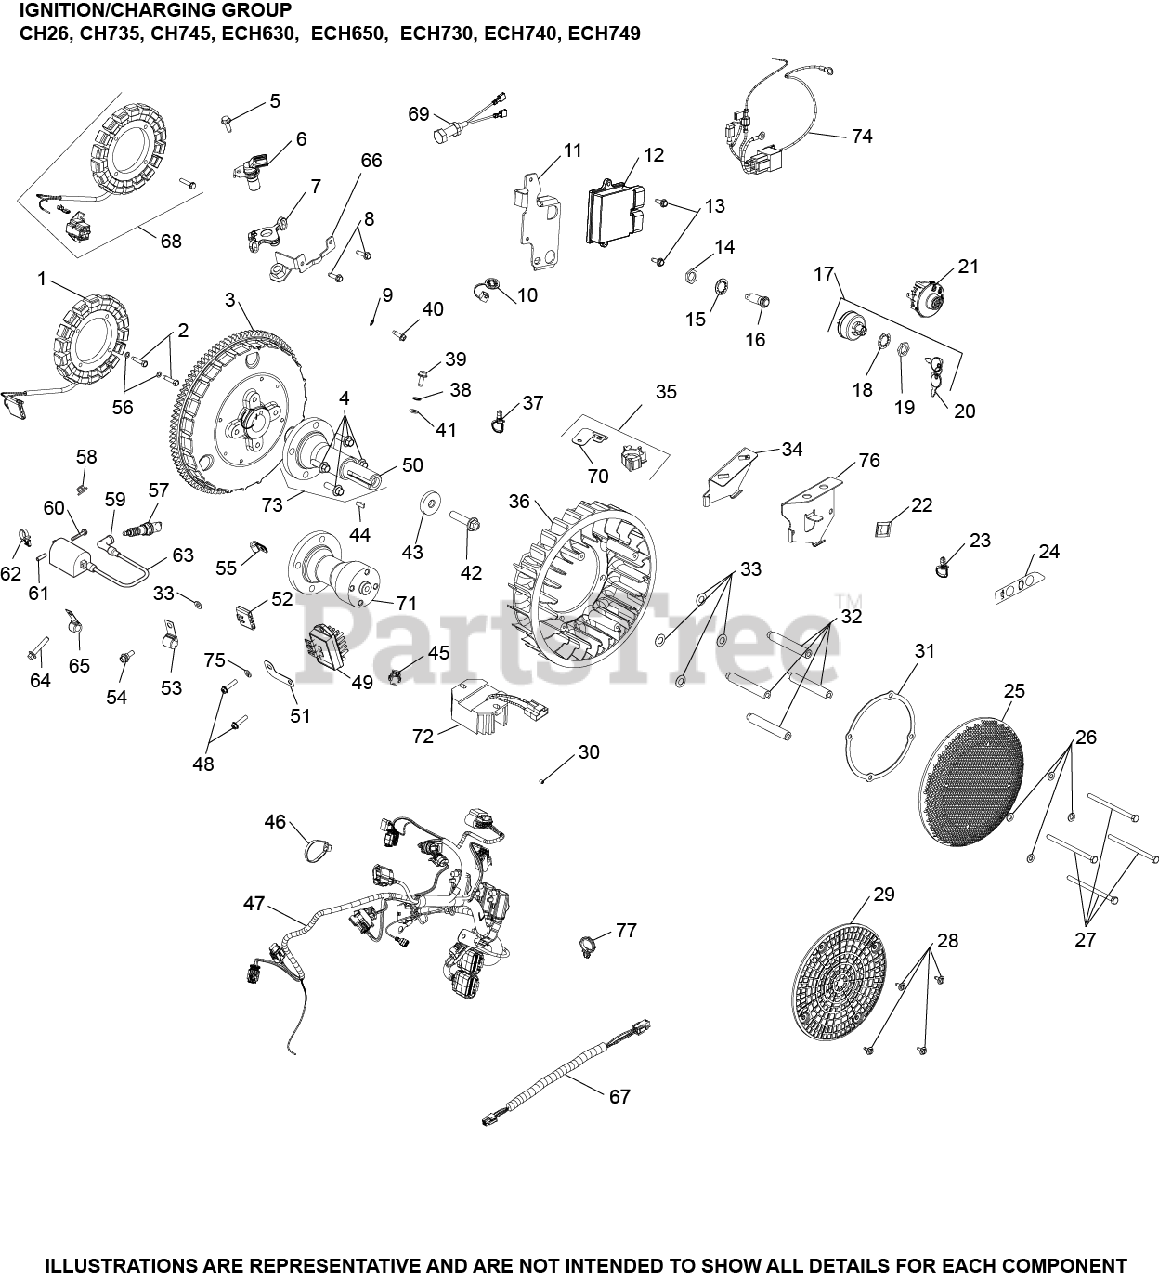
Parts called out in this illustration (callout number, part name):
1	KIT, 25 AMP STATOR ASSY.
2	SCREW, THREAD FORMING
3	FLYWHEEL ASSEMBLY
5	SCREW, THREAD FORMING
6	SENSOR, SPEED
7	BRACKET, SENSOR MOUNT-(#2512616S)
8	SCREW, THREAD FORMING
9	WASHER, INT TOOTH LOCK #10
10	CAP, CONNECTOR
11	BRACKET, ECU
12	MODULE, ECU
13	SCREW, THREAD FORMING
25	KIT, GRASS SCREEN
28	SCREW, FLG SEMS M4X.7X25
30	SCREW, FLG M10X1.5X45 - (#25086361S)
35	KIT, MOUNTING CLIP
36	FAN USE 24 755 253-S
38	WASHER, INT TOOTH LOCK 1/4"
41	WASHER, FLAT 1/4" (O.D. 1/2")
43	WASHER, FLAT 13/32"
44	KEY, 3/16" X 5/8"
48	SCREW, HEX FLANGE HI-LO
49	REGULATOR, RECTIFIER USE 25 403 32-S
52	CONNECTOR
54	BOLT, SHOULDER
56	WASHER, FLAT 3/16"
57	PLUG, SPARK (STD)
62	CLIP, SNAP-IN
63	COIL, IGNITION - EFI
64	SCREW, FLG M6X1.0X34
66	BRACKET, SENSOR MOUNTING
69	KIT, SPEED SENSOR
70	CLIP, MOUNTING BRACKET USE 25 154 21-S
75	WASHER, LOCK
